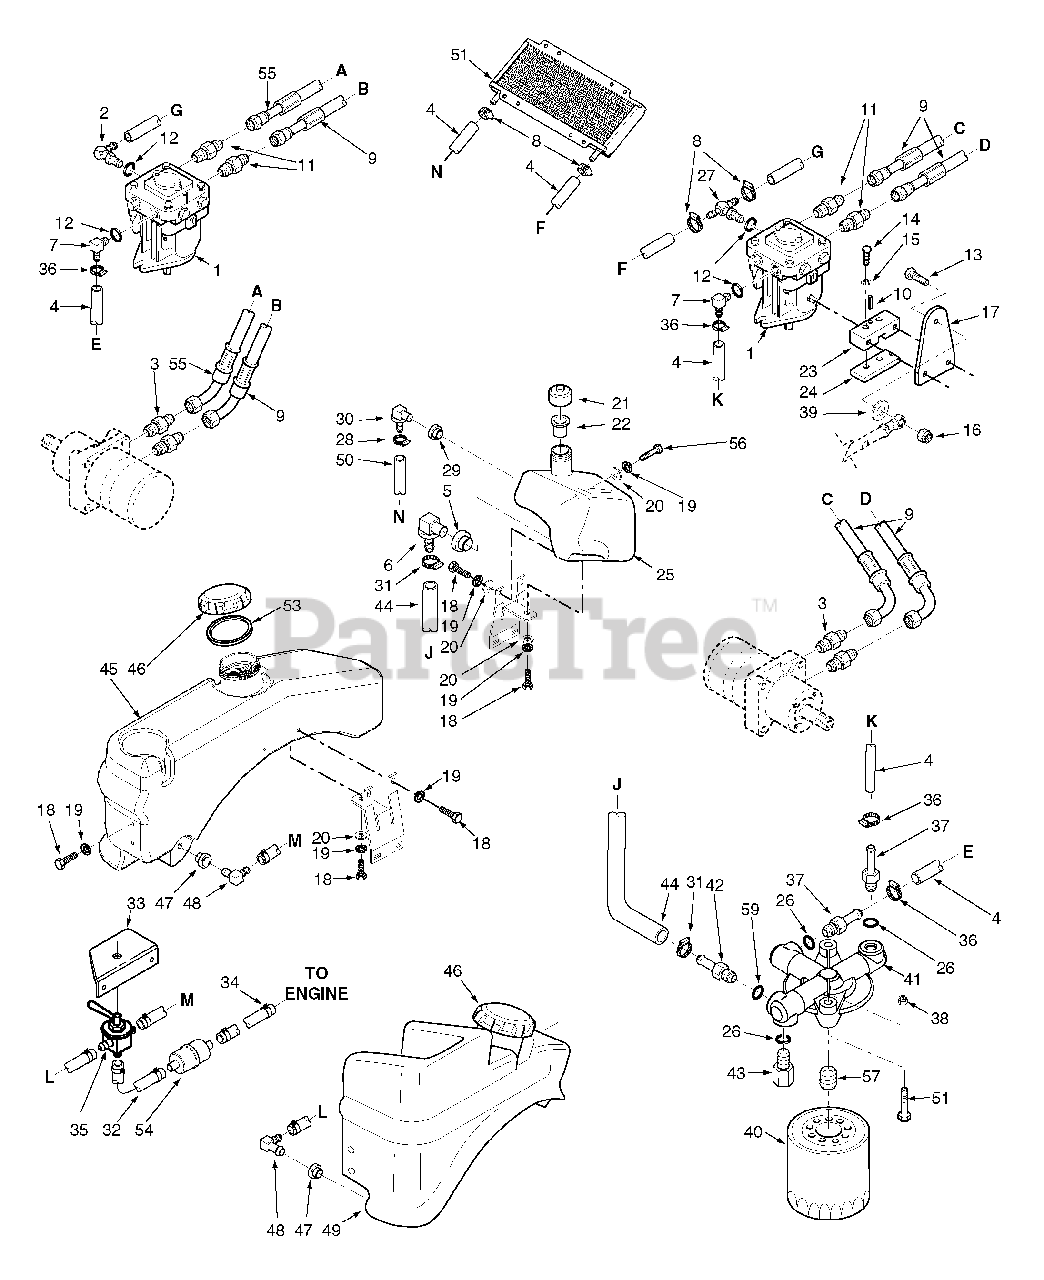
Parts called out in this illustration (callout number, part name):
1	Pump, BDP-10A-316 (LH)
2	Elbow, 90 Degree 9/16 O-Ring x 3/8 Hose
3	Fitting, 1/2" JIC x 5/8 O-Ring
4	Hose, 3/8 Pushlock (Specify length)
5	Bushing
6	Fitting
7	Elbow, 90 Degree 9/16 O-Ring x 3/8 Hose
8	Hose Clamp, .69 Dia.
9	Hose Assembly
10	Roll Pin
11	Fitting, 1/2" JIC x 1/2" O-Ring
12	O-Ring
13	Bolt, Hex Head 3/8-16 x 1-1/2"
14	Bolt, Hex Head 1/4-20 x 1-1/4"
15	Lockwasher
16	Nut, Elastic Stop 3/8-16
17	Control Lever
18	Bolt, Hex Head 5/16-18 x 3/4"
19	Lockwasher, 5/16
20	Flatwasher, 5/16-.375 x .875 x .083
21	Cap, Hydraulic Tank
22	Insert, Filler Neck
23	Control Block
24	Clamp Plate
25	Hydraulic Tank Assembly w/fittings
26	O-Ring
27	Tee Fitting, O-Ring to Barb
28	Clamp, .69 Max. / .25 Min. Dia.
29	Bushing
30	Elbow, 0.38 Hose
32	Fuel Hose, 1/4 ID
33	Bracket Fuel Valve
34	Clamp, Fuel Hose 1/4 Hose ID
35	Valve, Fuel Shutoff
36	Clamp, .69 Max. / .25 Min. Dia.
37	Fitting, 9/16 O-Ring x 3/8 Hose
38	Nut, Serr. Flange 5/16-18
39	Flatwasher, 3/8-.391 x .938 x .105
40	Oil Filter
41	Filter Head Assembly
42	Fitting, 3/4 O-Ring x 3/8 Hose
43	Plug, 9/16-18 O-Ring
44	Hose, Filter Inlet
45	Fuel Tank RH
46	Cap, Fuel Tank
47	Tank Bushing
48	Elbow, 90 Degree
49	Fuel Tank LH
50	Hose, 3/8 Pushlock 15" Long
51	Cooler, Transmission
52	Screw, 1/4-20 x 2"
53	Gasket, Gas Tank Cap
54	Fuel Filter
55	Hose Assembly
56	Bolt, Hec Head 5/16-18 x 1-1/2
57	Nipple, Oil Filter 1.0-12 UNF-2A x 1-1/4"
58	Bolt, Hex Head 5/16-18 x 2"
59	O-Ring, 3/4"
